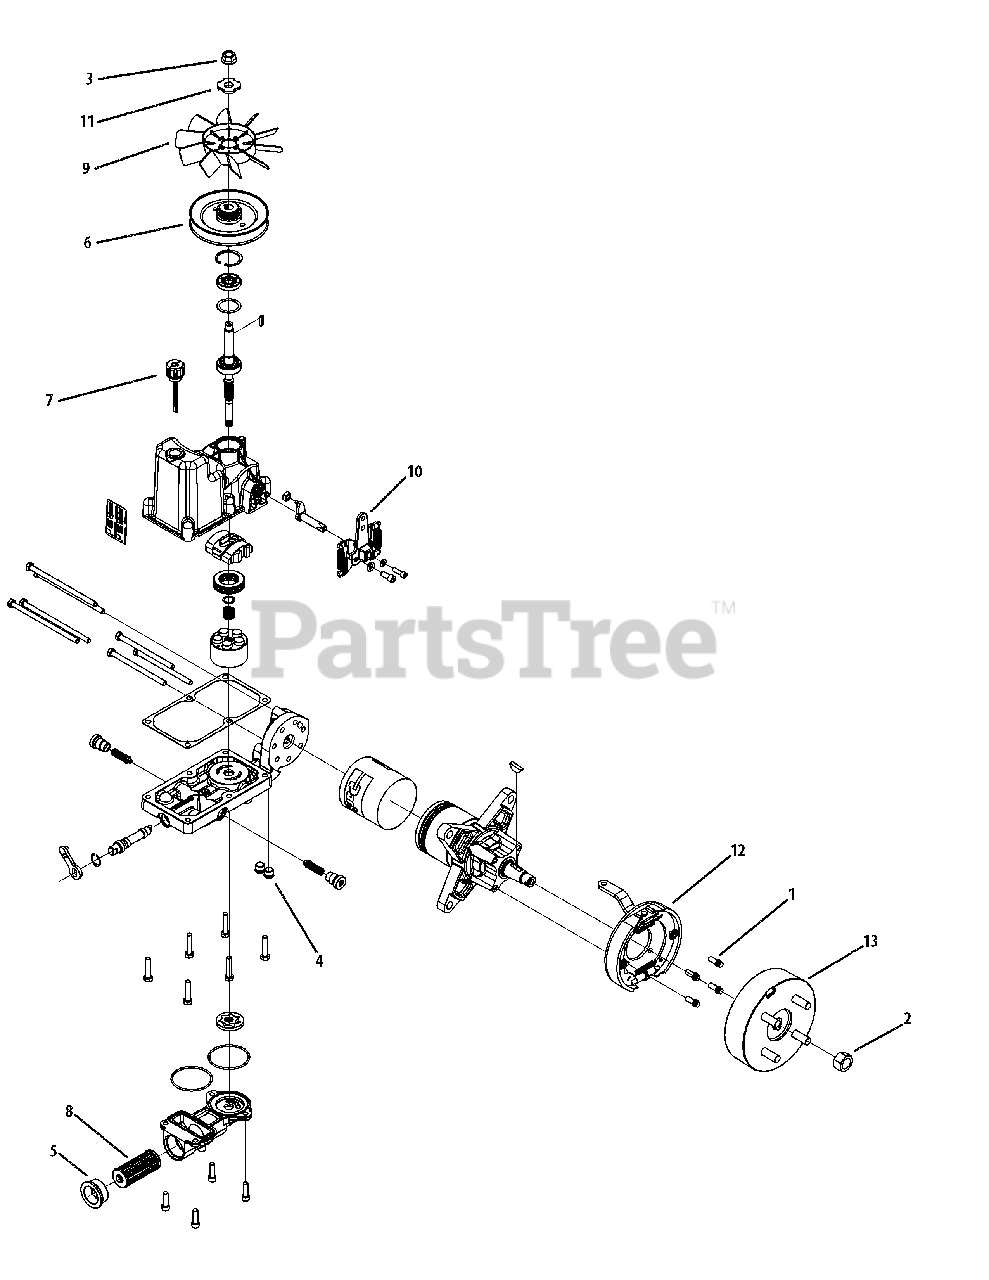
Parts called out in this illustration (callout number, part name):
1	Flange Head Screw
3	Nut, Flange 1/2-20 UNF
4	Plug, Magnetic Hex
5	Plug & O-Ring Assembly
6	Pulley (5")
7	Breather
10	SA, RTN
11	Fan Spacer
12	Brake Assembly
13	Drum Assembly, 4 Bolt, 1" Shaft
